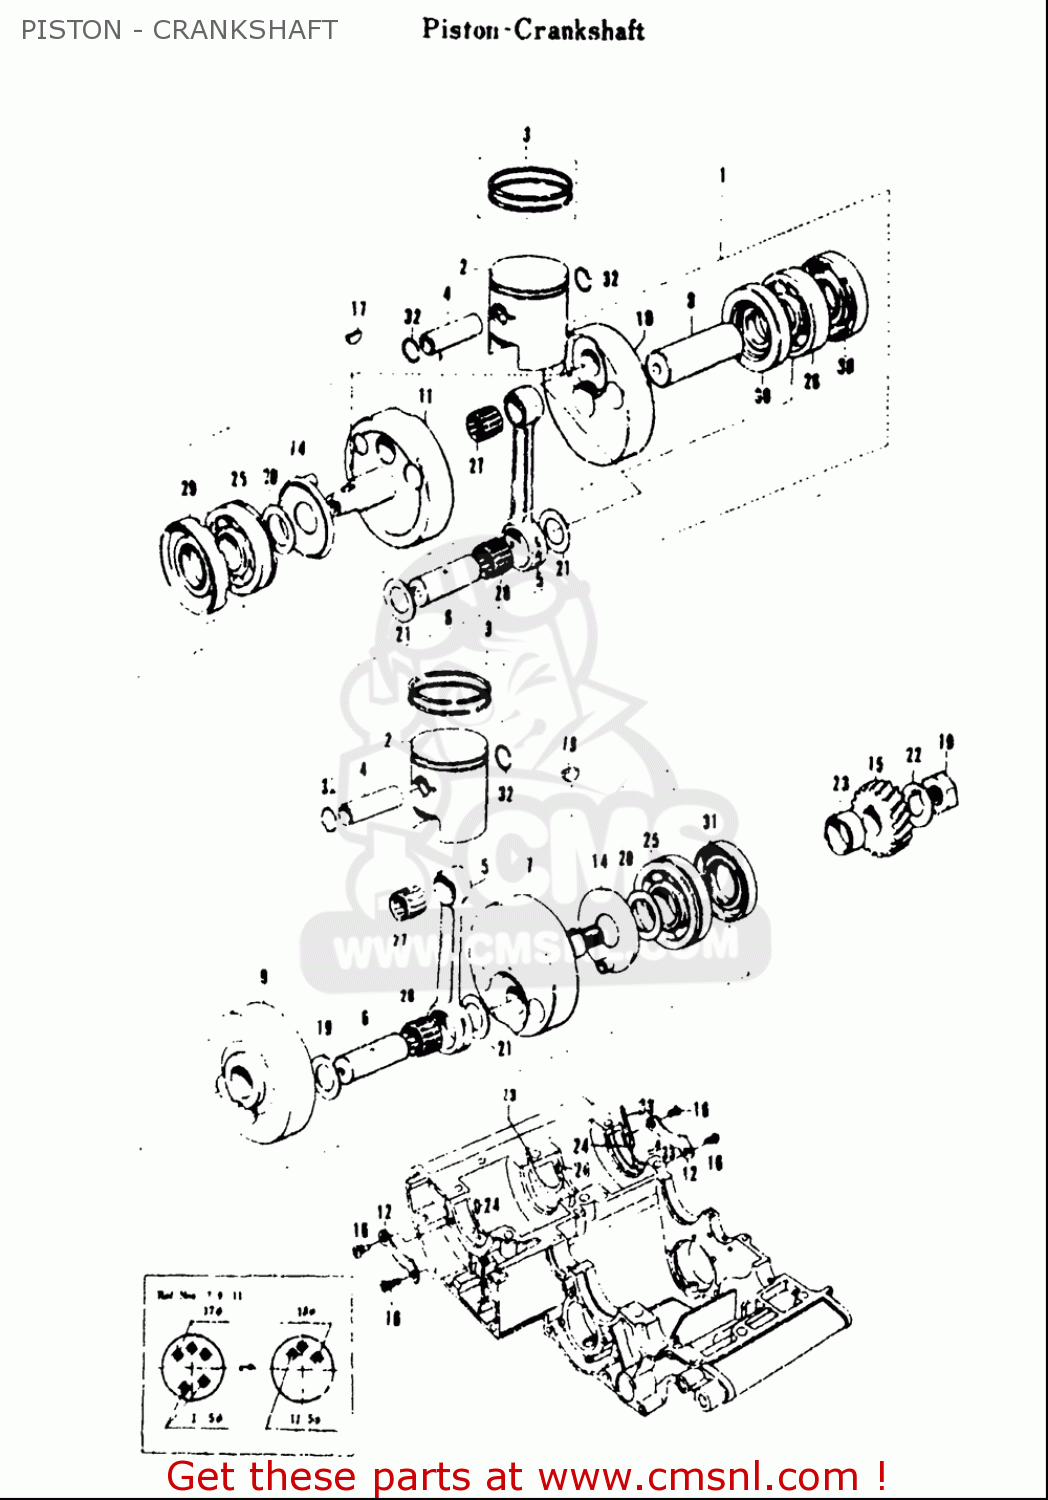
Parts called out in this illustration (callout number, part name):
2	PISTON SET(OS:0.5)
4	PIN,PISTON
5	CONNECTING ROD
6	PIN,CRANK
17	KEY
18	KEY
20	WASHER
21	SPACER,PRIMARY DRIVEN GEAR
23	PRIMARY DRIVE GEAR SPACER
24	ROLLER(4X13.8)
26	SEAL,OIL(25X52X5)
27	BEARING(14X18X19.8)
31	SEAL,OIL
32	RING,SNAP 14MM
